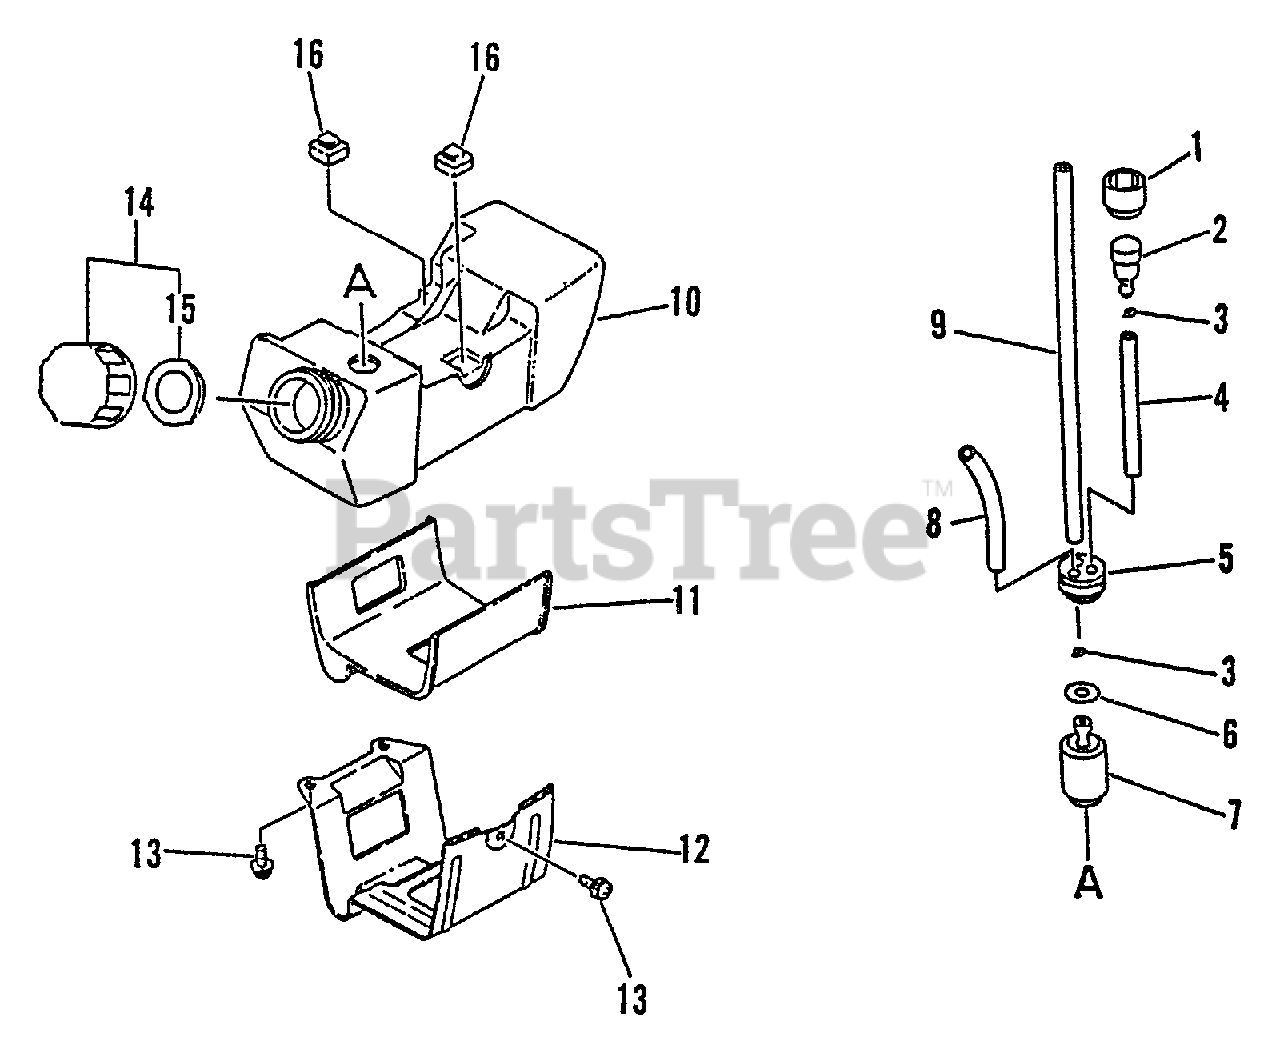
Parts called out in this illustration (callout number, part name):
1	COVER, VENT
2	VENT, FUEL TANK
3	CLIP - 5.5
4	PIPE - 3X6X70 -- BLACK
5	GROMMET
6	WASHER - 5
7	FILTER, FUEL
8	PIPE - 3X6X90 -- CLEAR
9	PIPE - 3X5X180 -- BLACK
10	TANK, FUEL
11	CUSHION
12	GUARD, FUEL TANK
13	SCREW - 5X10
14	CAP ASSY
15	GASKET, CAP
16	CUSHION
